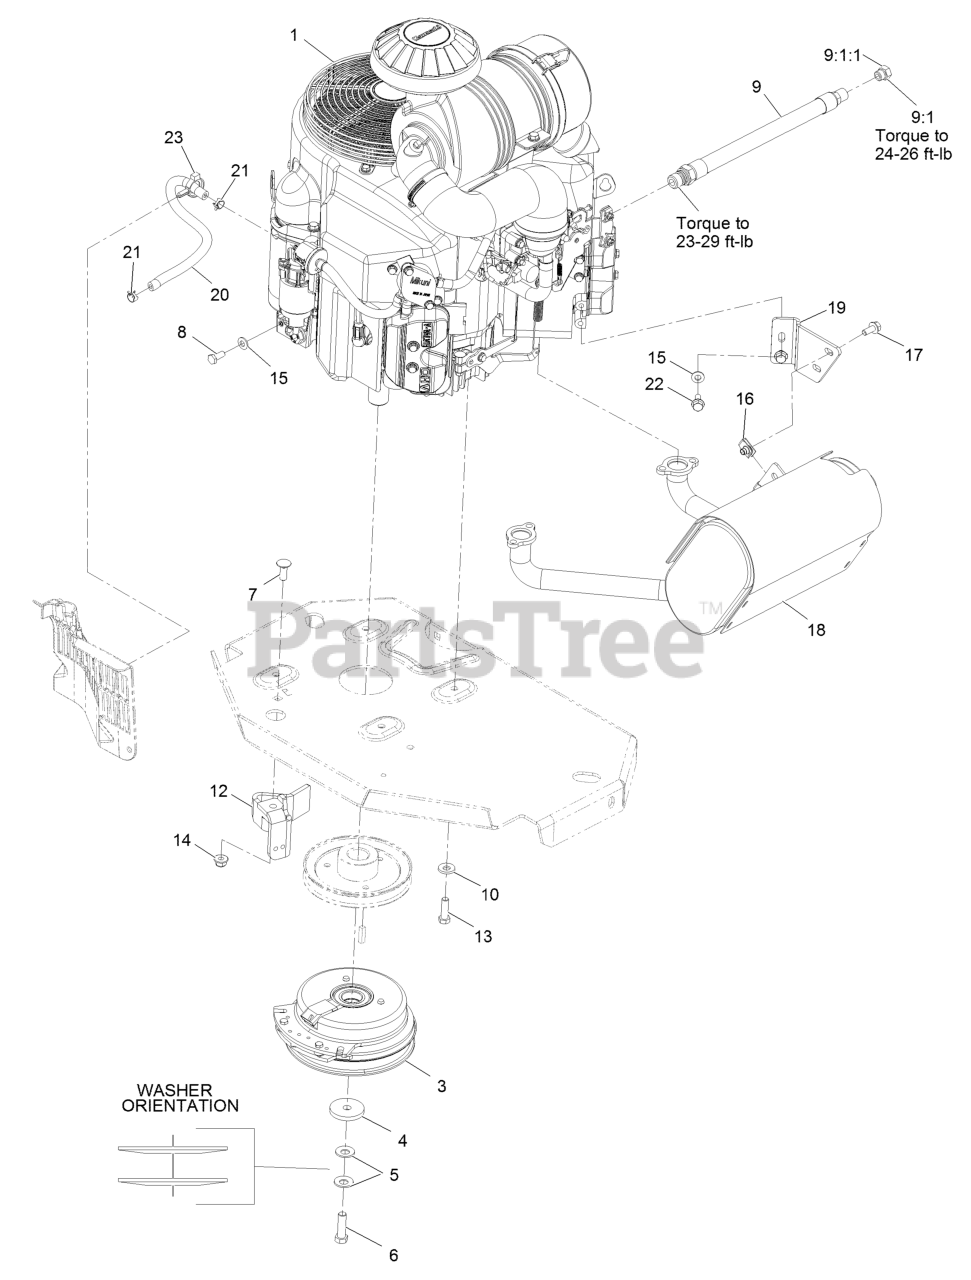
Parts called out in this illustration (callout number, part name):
3	CLUTCH KIT
4	WASHER-CLUTCH
5	WASHER-SPRING
6	SCREW-HH 7/16-20 X 1 1/2 W/LOCTITE
7	SCREW-CARR
8	SCREW-HH
9	ENGINE OIL DRAIN HOSE ASM
9:1	PLUG-HH
9:1:1	O-RING
10	WASHER-BELLEVILLE
12	CLUTCH-ANCHOR
13	SCREW-HH
14	NUT-HF, NI
15	WASHER-SPRING
17	SCREW-HHF
18	MUFFLER
19	BRACKET-MUFFLER
20	HOSE-FUEL
21	CLAMP-HOSE
22	SCREW-HHF
23	CLAMP-HOSE
